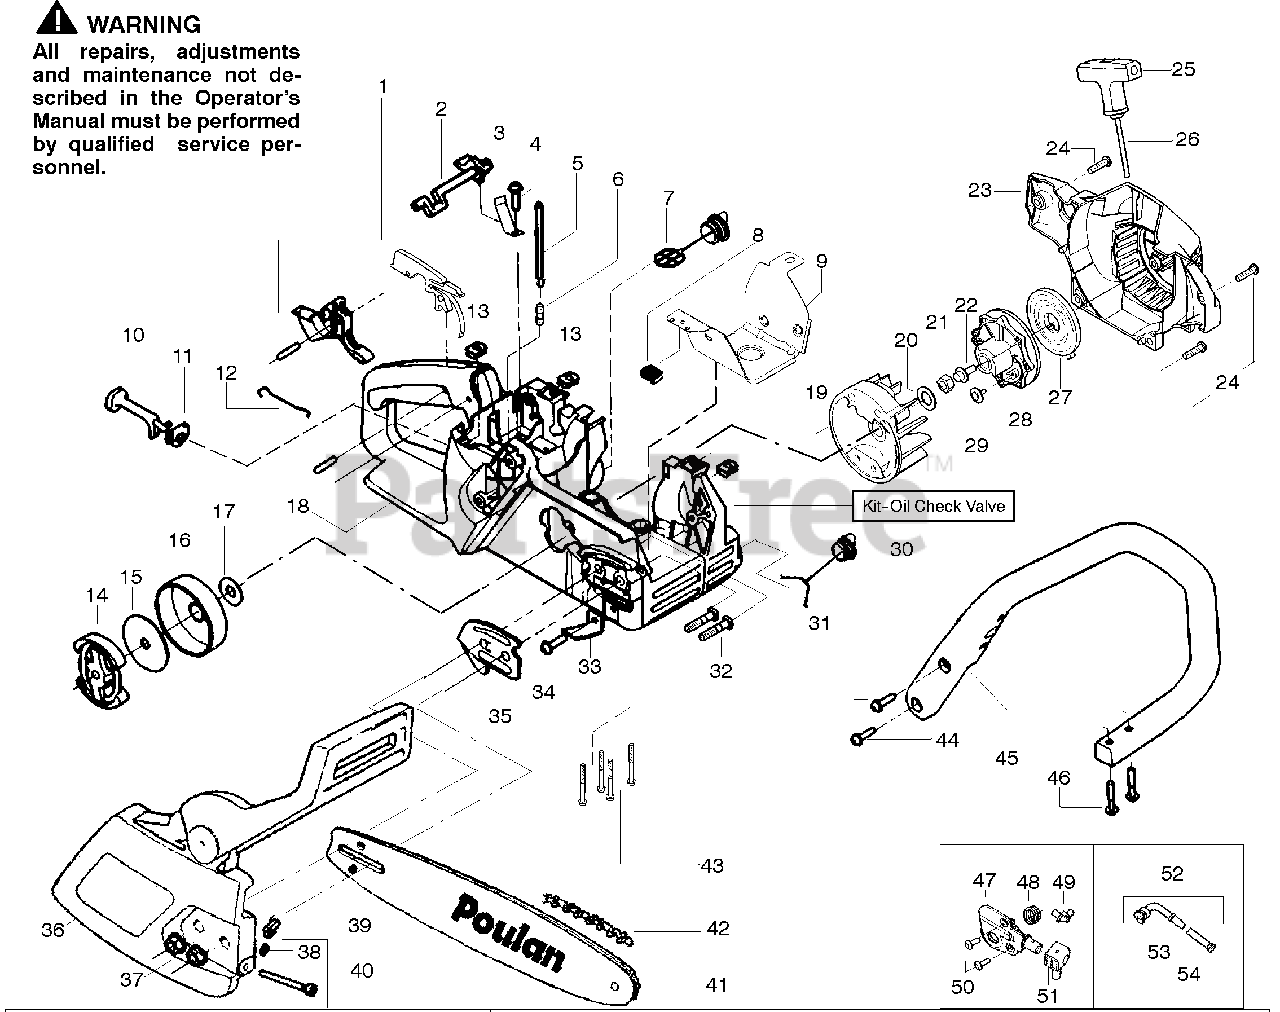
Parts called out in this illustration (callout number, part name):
1	Kit-Trigger & Lockout
2	Lever-Switch
3	Spring-Switch
5	Kit-Fuel Line (Large)
6	Fitting - Fuel line
7	Assy-Fuel Cap w/ret.
8	Clip - "U"
9	Shield - Heat
10	Lever-Choke
11	Grommet-Choke lever
12	Wire-Throttle
13	Nut-Speed
14	Assy.-Clutch
15	Washer-Clutch
16	Assy-Drum W/brg.
17	Washer - Thrust
18	Assy-Chassis
19	Assy-Flywheel
20	Washer-Flywheel
21	Nut-Flywheel
23	Housing-Fan
25	Handle-Starter
26	Kit-Rope
27	Spring-Starter
28	Pulley-Starter
30	Kit-Oil Check Valve
31	Assy-Oil Cap
32	Bolt - Bar
33	Chain Catcher
35	Plate-Bar Mounting
36	Assy.-Chain Brake
37	Nut-Bar Mounting
38	Retainer-Bar Adjust
39	Pin-Bar Adjust
40	Kit-Bar Adjust
41	Bar- 16"
42	Chain- 16"
45	Handle-Front
47	Kit-Oil Pump
48	Gear-Worm Spring
49	Elbow-Oil Pickup
51	Block-Seal
52	Assy-Oil-Pickup
53	Pickup-Oiler
54	Filter-Oil
